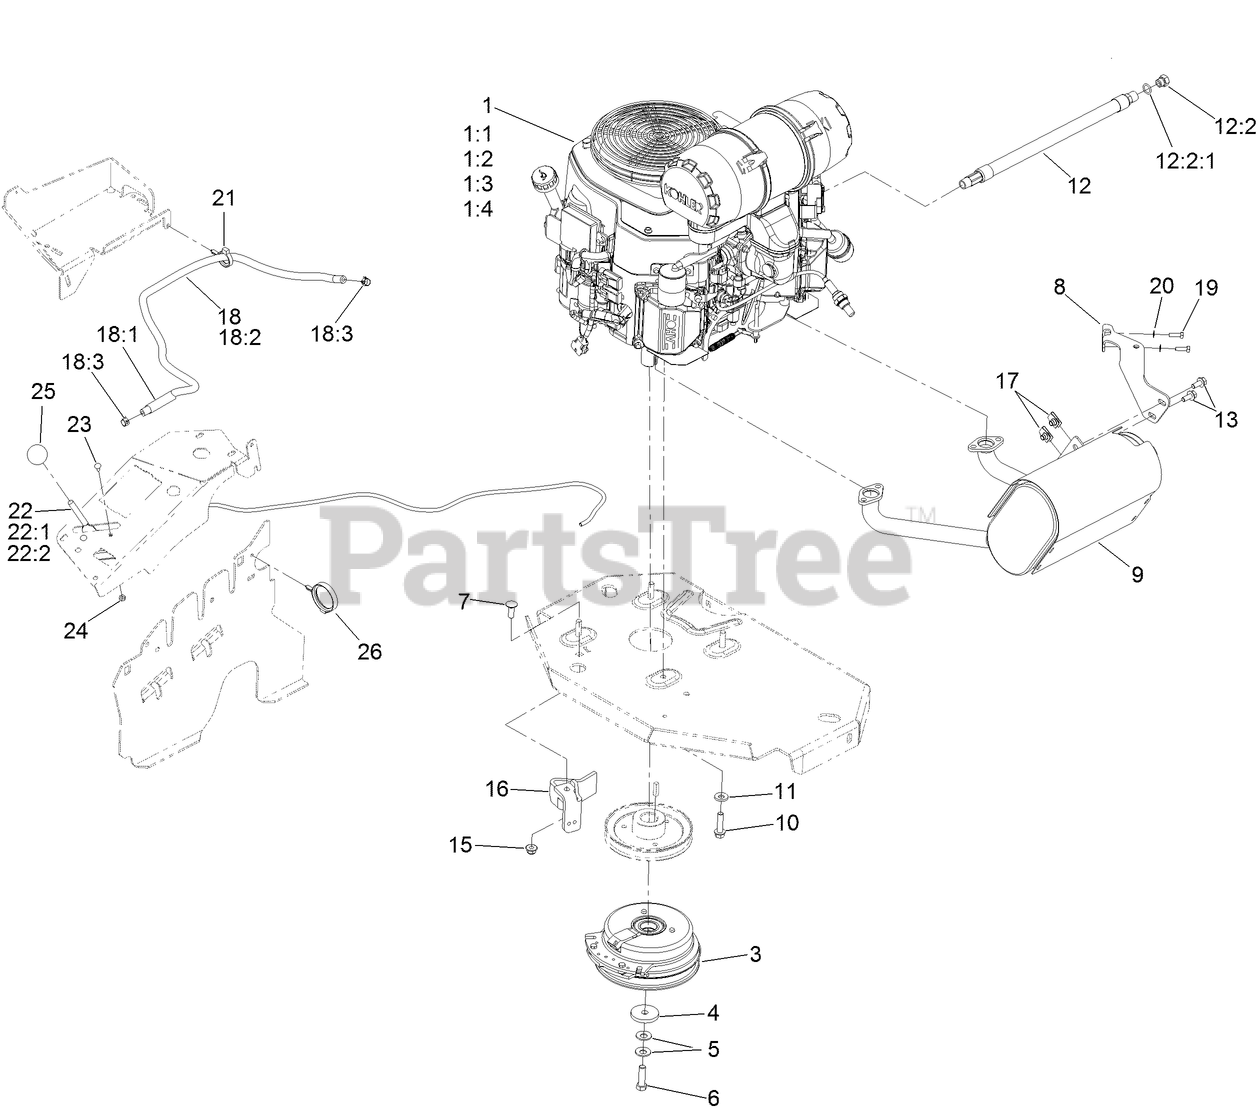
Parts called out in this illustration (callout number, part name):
1:1	KOHLER 52 050 02-S ENGINE OIL FILTER
1:2	KOHLER 25 083 01-S ENGINE AIR FILTER
1:3	KOHLER 25 083 04-S SAFETY FILTER
1:4	KOHLER 25 050 42-S FUEL FILTER
3	CLUTCH KIT
4	WASHER-CLUTCH
5	WASHER-SPRING
6	SCREW-HH, W/LOCTITE
7	SCREW-CARR
8	MUFFLER BRACKET KIT
9	MUFFLER KIT
10	SCREW-HWH
11	WASHER-BELLEVILLE
12	OIL DRAIN HOSE ASM
12:2	PLUG-HH
12:2:1	O-RING
13	SCREW-HH
15	NUT-HF, NI
16	CLUTCH-ANCHOR
17	NUT-U
18	FUEL LINE ASM
18:1	HOSE-FUEL
18:2	SLEEVE-THERMAL
18:3	CLAMP-HOSE
19	SCREW-HH
20	WASHER-SPRING
21	CLAMP-HOSE
22	THROTTLE CONTROL ASM
22:1	LEVER-THROTTLE
23	BOLT-CARR
24	NUT-LOCK, NI
25	KNOB-BALL
26	CLAMP-HARNESS
